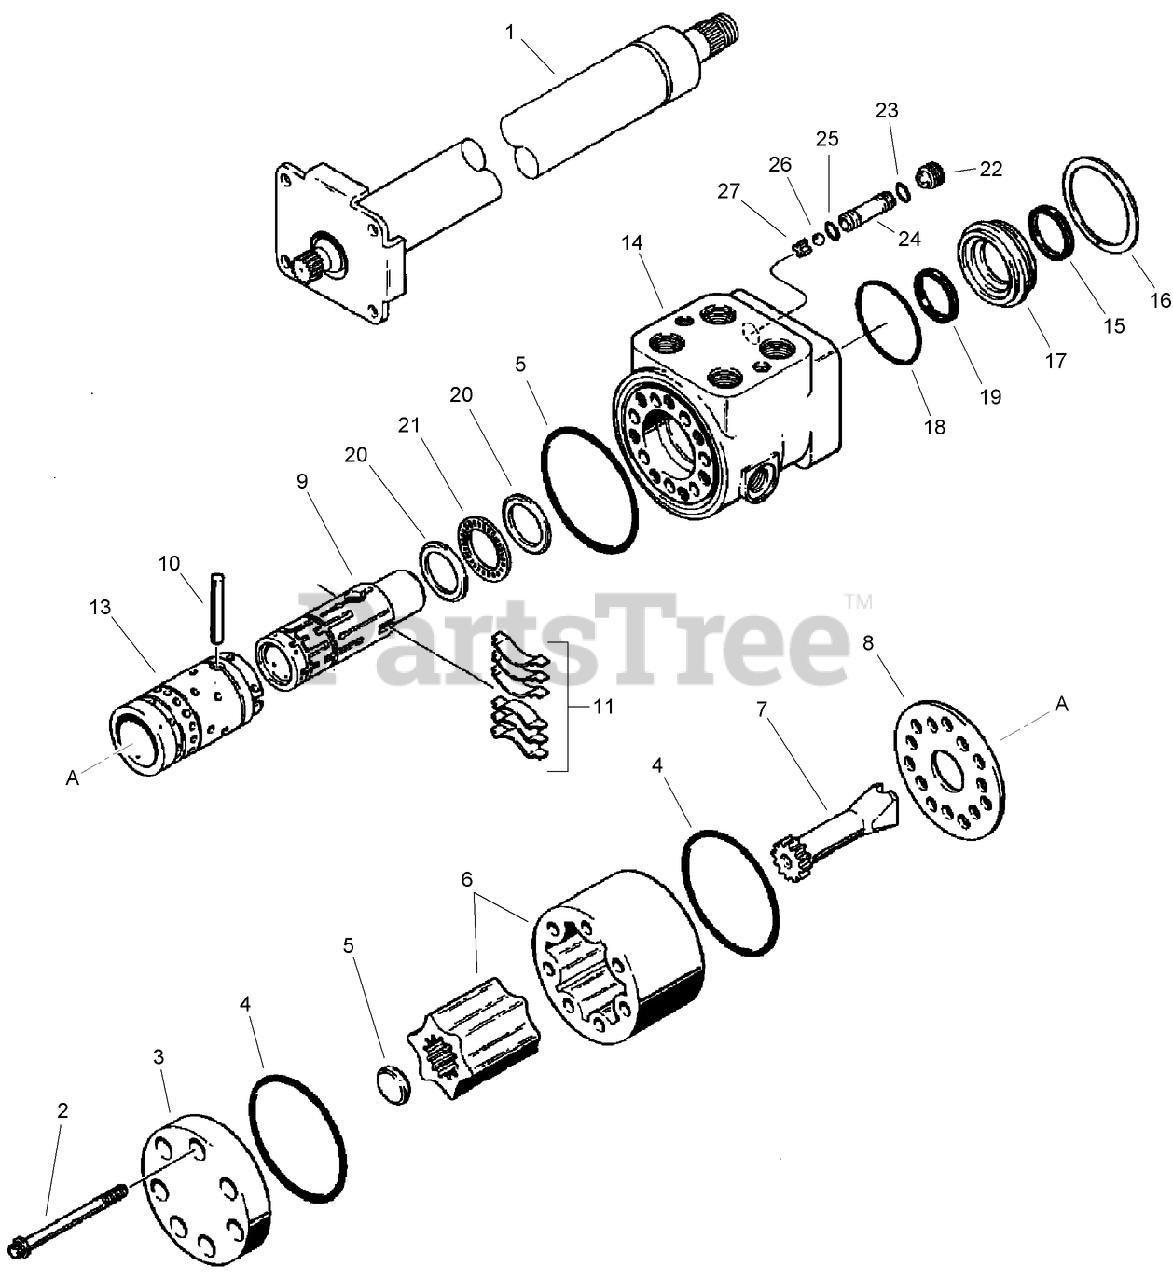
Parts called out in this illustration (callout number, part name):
1	STEERING COLUMN ASM
2	BOLT-5/16 x 1-3/4
3	COVER-End
4	O-RING-End Cap, 2-7/8 ID x 1/16
5	SPACER-Drive Shaft
6	GEROTOR
7	SHAFT-Drive, Gerotor
9	Spool
10	PIN-Roll
11	SPRING
12	SPACER (If used)
13	Sleeve
14	Body-Valve
15	SEAL-Outer, 1 ID
17	BUSHING
18	O-RING-1-7/8 ID x 1/8
19	SEAL-Square Section, Outer
20	RACE-Bearing, Thrust
21	BEARING
22	SETSCREW
23	O-RING-Outer, 3/8 ID x 1/16
24	SEAT-Ball
25	O-RING-Inner
26	BALL-Chrome Alloy Steel, 5/16, Grade 24
27	RETAINER-Check Ball
